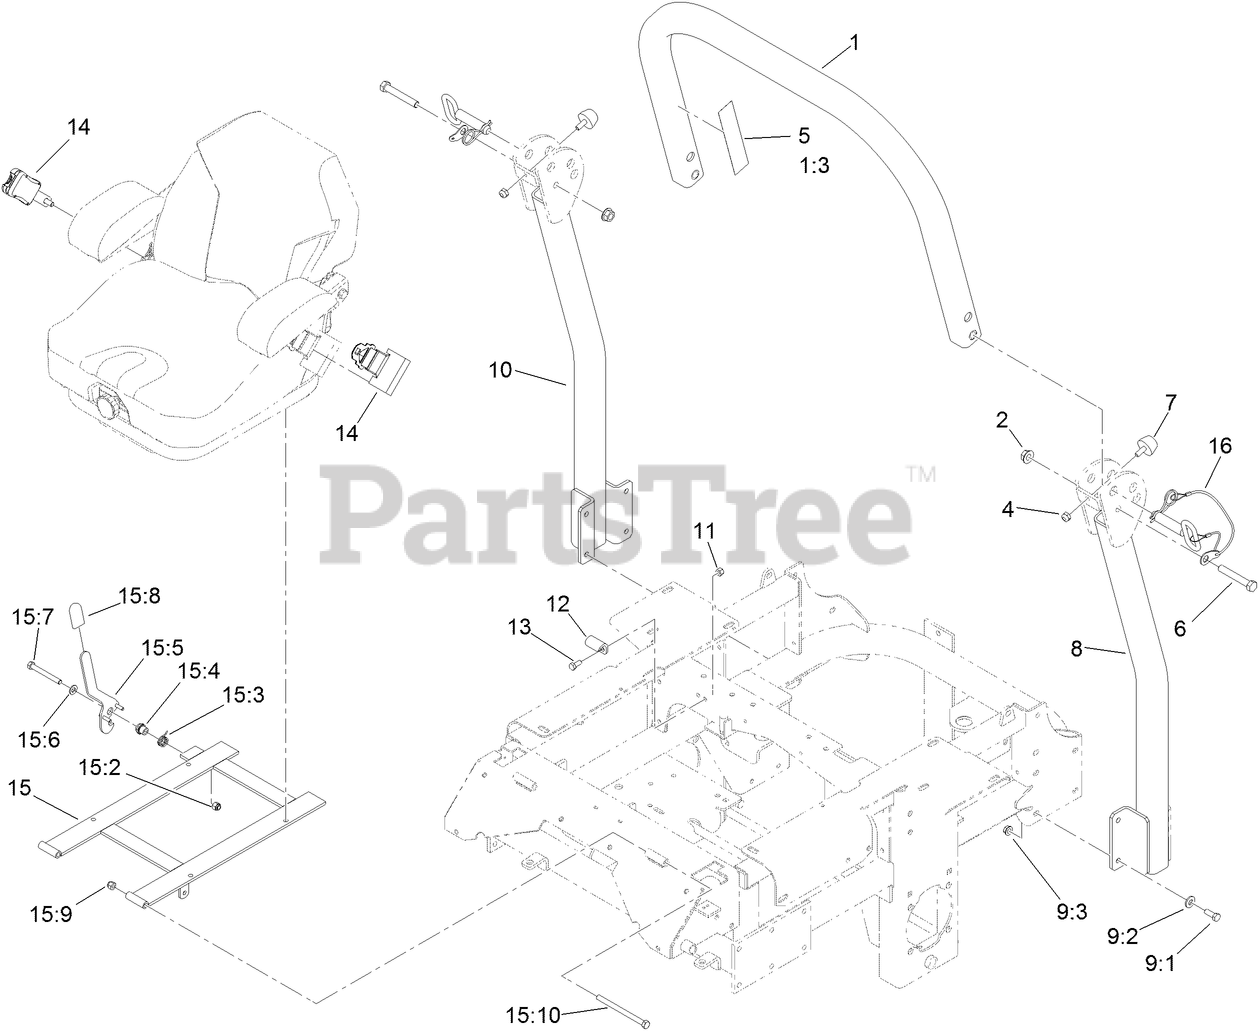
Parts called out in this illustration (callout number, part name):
1	HUB and BEARING ASM
1:3	DECAL-WARNING, FOLDING ROPS
2	NUT-HF
4	NUT-LOCK, NI
5	DECAL-WARNING
6	SCREW-HH
7	BUMPER-RUBBER
8	HUB and BEARING ASM
9	HUB and BEARING ASM
9:1	SCREW-HH
9:2	WASHER-BELLEVILLE
9:3	NUT-HHF, WHIZ
10	HUB and BEARING ASM
11	NUT-LOCK, NI
12	CATCH-LATCH, SEAT
13	SCREW-HH
14	SEAT BELT SERVICE KIT
15	SEATFRAME ASM
15:2	NUT-LOCK, NI
15:3	SPRING-TORSION
15:4	BUSHING-LATCH, SEAT
15:5	LATCH ASM
15:6	WASHER-FLAT
15:7	SCREW-HH
15:8	GRIP-LEVER
15:9	NUT-LOCK, NI
15:10	SCREW-HH
16	PIN-FOLD, ROPS
